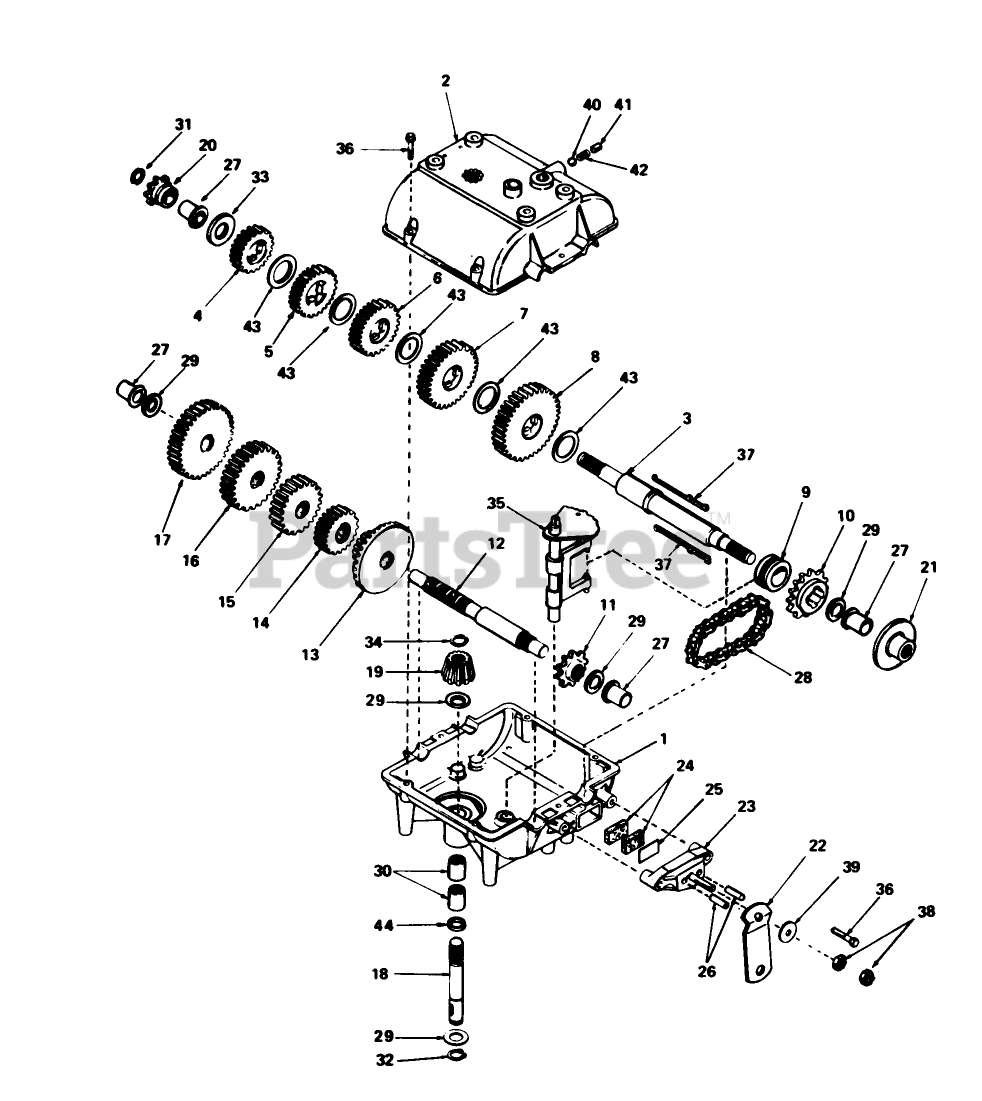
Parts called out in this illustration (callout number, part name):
1	Case-Transmission
2	Cover-Transmission
3	Shaft-Output Brake
4	Gear-Spur 20 teeth
5	Gear-Spur (22 teeth)
6	Gear-Spur, 25 Teeth
7	Gear-Spur, 30 Teeth
8	Gear-Spur, 35 Teeth
9	Collar-Shift
10	Sprocket-18 Teeth
11	Sprocket-9 Teeth
12	Countershaft
13	Gear-Bevel (42 tooth 15 tooth spur gear)
14	Gear-Spur, 20 Teeth
15	Gear-Spur, 25 Teeth
16	Gear-Spur (28 teeth)
17	Gear-Spur (30 teeth)
18	Shaft-Input
19	Bevel Pinion-Input
20	Sprocket (8Teeth)
22	Lever Brake
23	Holder-Brake Pad
24	Brake Pad
25	Brake Pad Plate
26	Dowel Pin
27	Bushing, Flanged
28	Chain-Roller #41
29	Washer
30	Bearing-Needle
31	Piston Asm (.020 O S)
32	Ring-Snap
33	Washer
34	Ring-Retainer
35	Rod and Fork ASM
36	Ring Set (.020 O S)
38	Locknut
39	Washer
40	Ball-Steel
41	Screw-Set
42	Spring
43	Washer
44	O Ring
